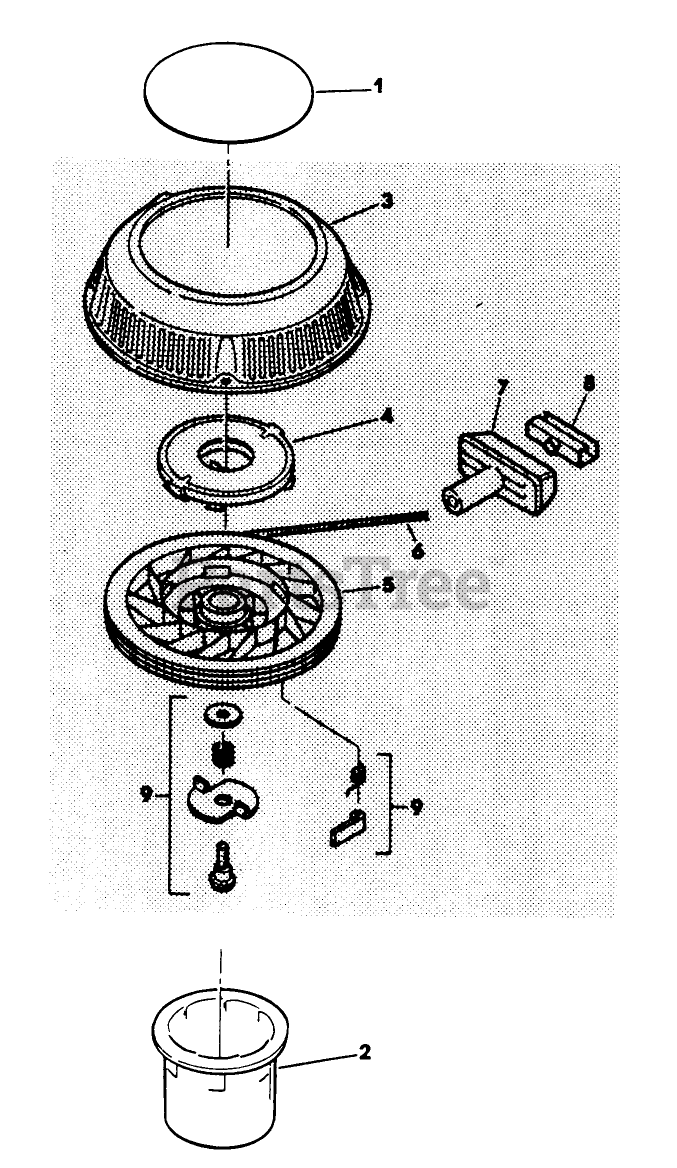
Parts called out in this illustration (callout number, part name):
2	HUB-STARTER E COMM.
5	PULLEY
8	CLIP-STARTER
9	DOG KIT
